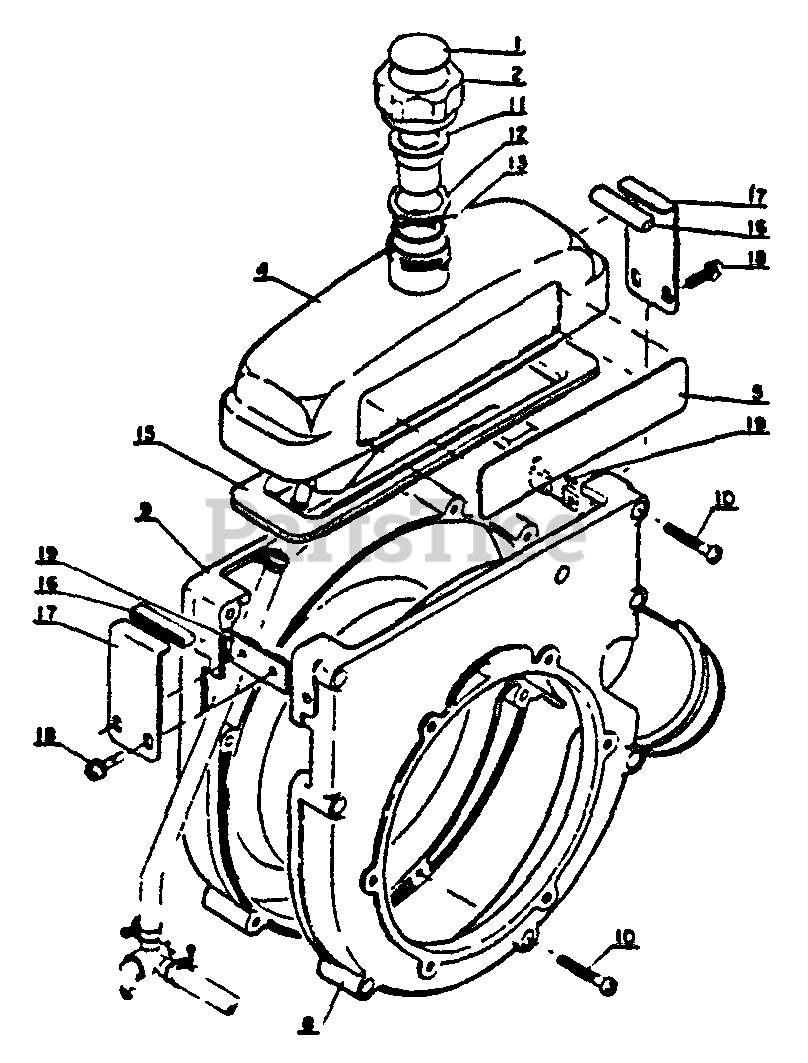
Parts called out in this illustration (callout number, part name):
1	LABEL - FUEL MIX
2	CAP
4	TANK, FUEL
5	LABEL - NAME
8	COVER, FAN - OUTER
9	COVER, FAN - INNER
10	SCREW - 5X35
11	CUP
12	GASKET, CAP
13	O-RING - 25
15	SEAL
16	CUSHION
17	BRACKET, FUEL TANK
18	SCREW - 5X18
19	WASHER
